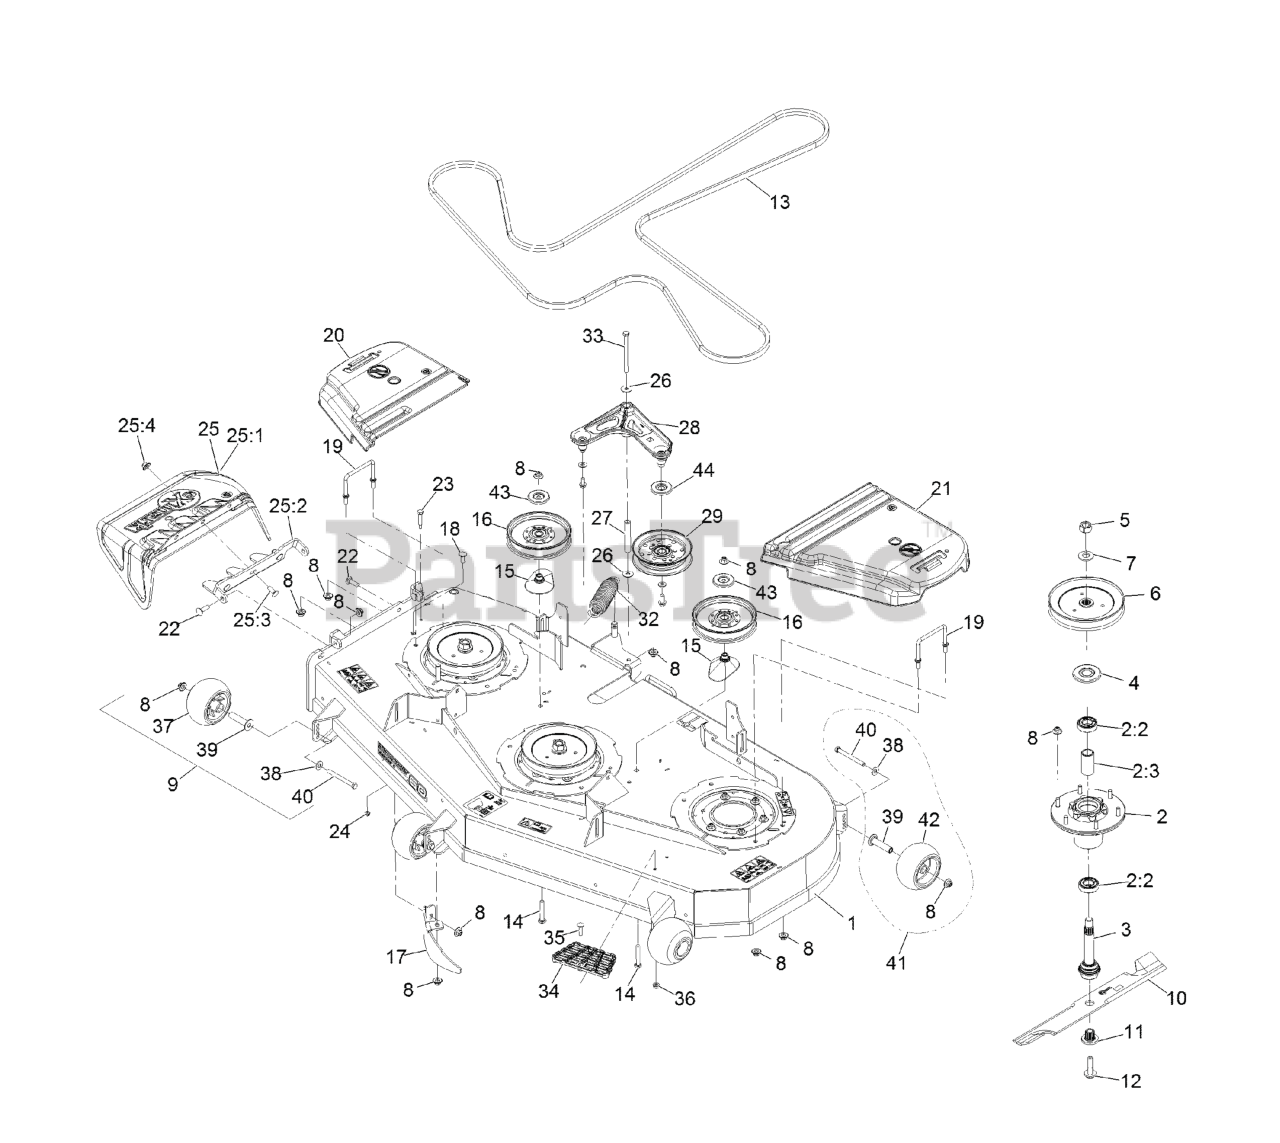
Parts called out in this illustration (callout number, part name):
1	ASM-DECK W/DECALS 604
2	ASM-CUTTER HSG WITH BEARINGS
2:2	BEARING-BALL
2:3	SPACER-BEARING
3	ASM-SPINDLE AND SEAL
4	GUARD,BEARING TOP .989
5	NUT-HEX
6	SHEAVE,BLADE DRIVE 7.25
8	Nut-Nyloc 3/8-16 Flg
9	KIT, ANTI-SCALP ROLLER
10	Blade-Extreme 2, 20.50"
11	BUSHING,SPLINED
12	SCREW,SEMS 1/2-20 X 2.19
13	BELT-V
14	SCREW-CARR
15	SPACER-PULLEY
16	IDLER-PULLEY, FLAT 6.00X1
17	DOGLEG - LZ60
18	SCREW-CARR
19	WIREFORM-COVER
20	COVER-BELT, RH
21	COVER-BELT, LH
22	BOLT-CARR
23	BOLT-SHOULDER
25	ASM,DISCHARGE CHUTE
25:1	CHUTE,DISCHARGE
25:2	BRACKET,DISCHARGE CHUTE
25:3	SCREW-CARR
25:4	Nut-Nyloc 3/8-16 Flg
27	BUSHING
28	IDLER ARM ASM
29	IDLER-PULLEY, FLAT
32	SPRING-EXTENSION
33	SCREW-HH
34	STEP-DECK
35	Bolt-Carriage 5/16-18 X 1 1/4
36	NUT-HF, NI
37	ROLLER-SCALP, ANTI
38	WASHER-BELLEVILLE
39	AXLE, ROLLER
40	SCREW-HH 3/8-16 X 3 3/4 GR 8
41	KIT-ANTISCALP ROLLER
42	ROLLER-SCALP, ANTI
43	SHIELD-DUST
44	SHIELD-GUARD, DUST
